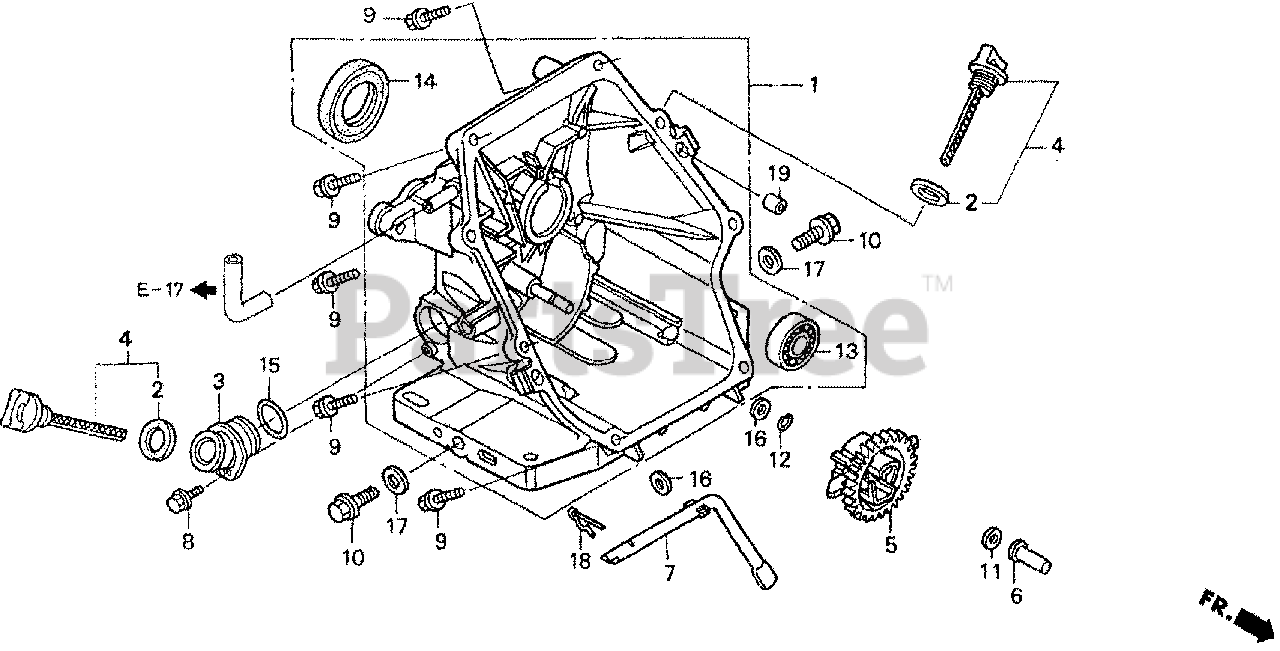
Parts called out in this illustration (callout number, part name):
1	COVER ASSY., CRANKCASE
2	GASKET, OIL FILLER CAP
3	EXTENSION, OIL FILLER
4	DIPSTICK, OIL
4	GAUGE ASSY., OIL LEVEL
5	GOVERNOR ASSY.
6	SLIDER, GOVERNOR
7	SHAFT, GOVERNOR ARM
8	BOLT, FLANGE (6X14) (CT200)
9	BOLT, FLANGE (6X25)
10	BOLT, DRAIN PLUG
11	WASHER, THRUST (6MM)
12	CLIP, GOVERNOR HOLDER
13	BEARING, RADIAL BALL (62/28)
14	OIL SEAL (28X41.25X6)
15	O-RING (22.5X2.2)
16	WASHER, PLAIN (6MM)
17	WASHER, DRAIN PLUG (12MM)
18	PIN, LOCK (8MM)
19	PIN, DOWEL (8X20)
